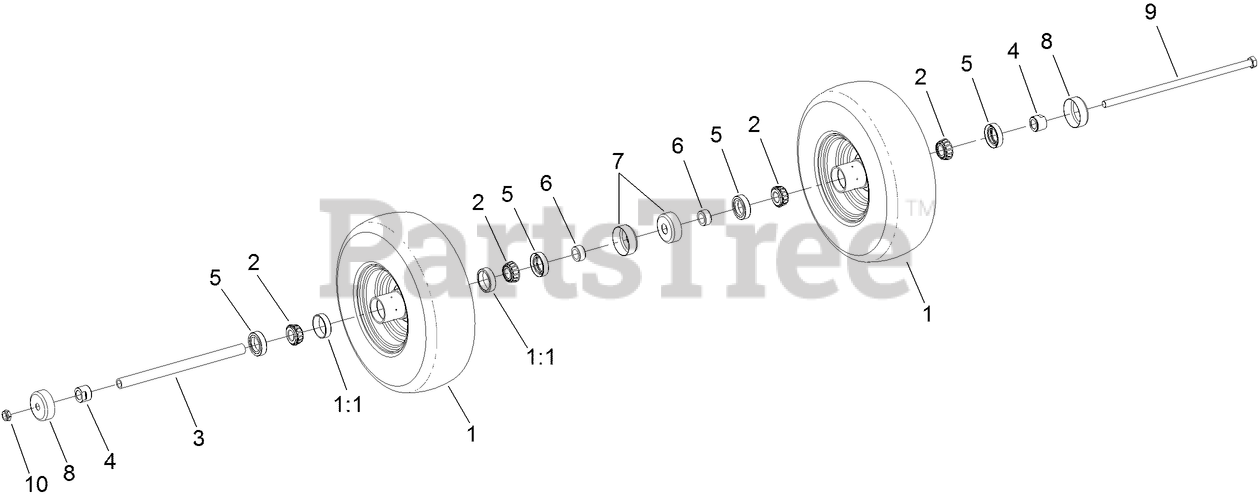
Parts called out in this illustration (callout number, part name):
1	WHEEL AND TIRE ASM
1:1	BEARING-CUP
2	BEARING-CONE, TAPER
3	AXLE-CASTER
4	SPACER-NUT
5	SEAL-CASTER
6	SPACER-CASTER, DUAL
7	GUARD-SEAL
8	GUARD-SEAL
9	SCREW-HH
10	NUT-LOCK, NI
